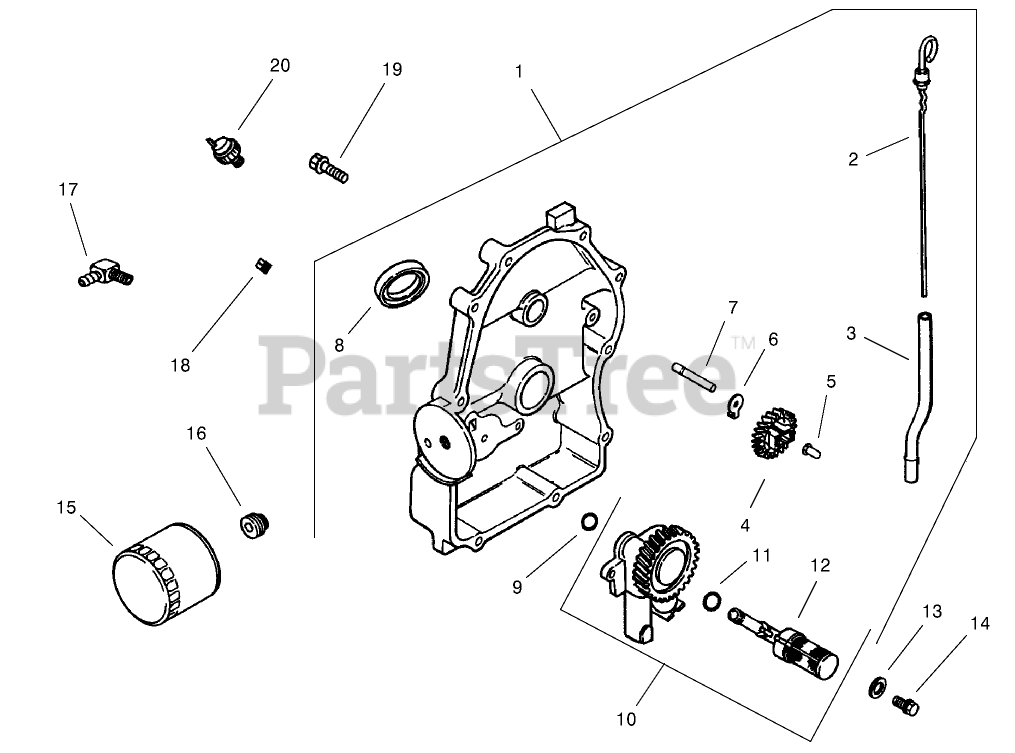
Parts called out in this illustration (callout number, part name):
1	Plate, closure assembly (Includes 2-12)
2	Dipstick
3	Tube-Dipstick
4	Kit, governor gear (Includes 5)
5	Pin-Governor
6	Tab-Locking
7	Shaft-Gear, Governor
8	Seal-Oil
9	O Ring
10	Oil pump assembly (Includes 11,12)
11	O-Ring
12	Pick Up-Oil
13	Washer
14	Screw
15	Filter-Oil
16	Nipple-Filter, Oil
17	Connector
18	Plug
19	Screw
20	Switch-Pressure
